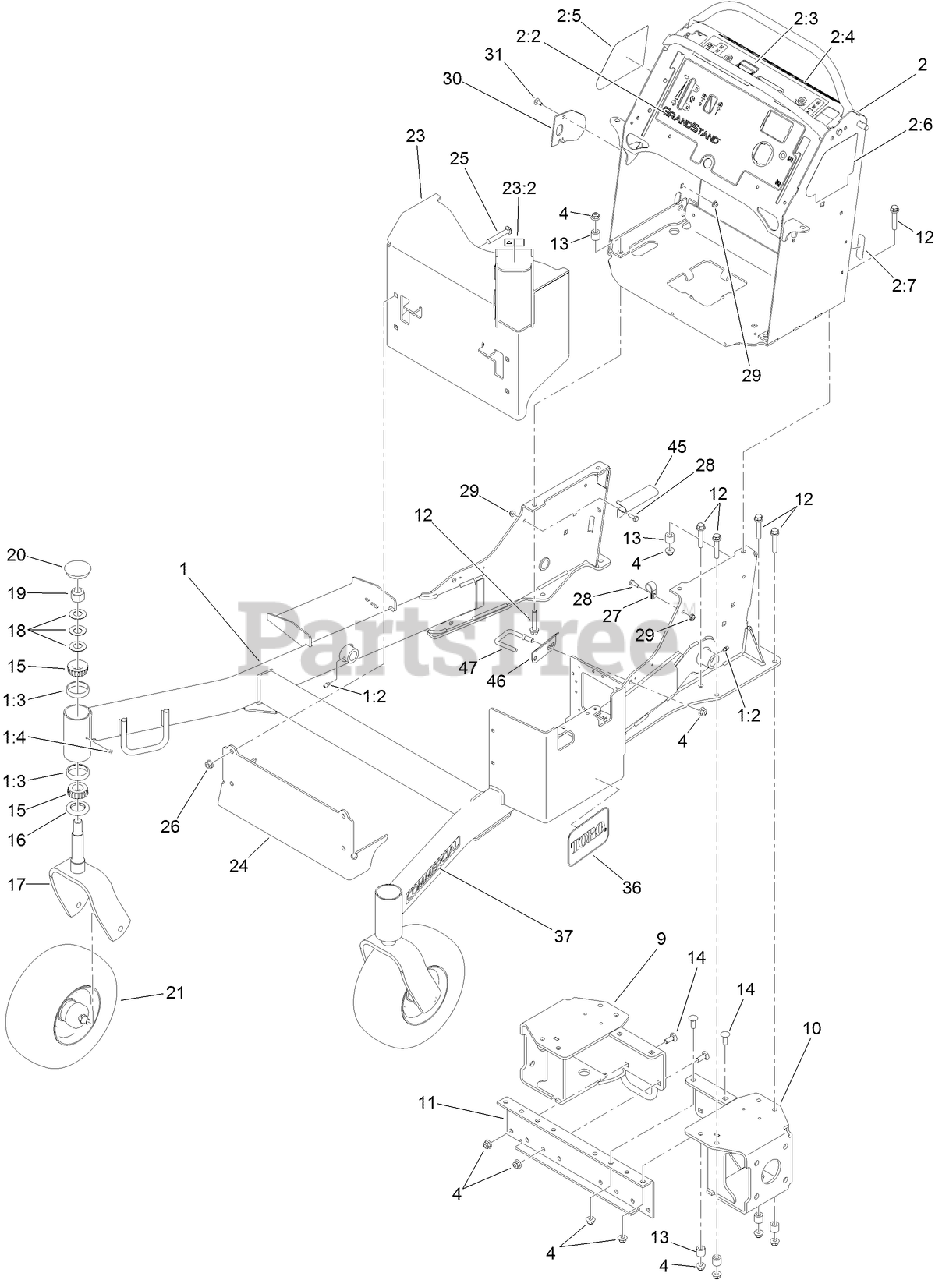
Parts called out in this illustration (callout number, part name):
1	FRONT FRAME ASM
1:2	FITTING-GREASE
1:3	CUP-BEARING
2	CONTROL TOWER ASM
2:2	DECAL-CONTROL PANEL, EFI
2:3	DECAL-OPC
2:4	DECAL-WARNING
2:5	DECAL-HOC
2:6	DECAL-SERVICE/SPARK ARREST
2:7	DECAL-FUSE
4	NUT-HF, NI
9	MOUNT-MOTOR, RH
10	MOUNT-MOTOR, LH
11	MOUNT-MOTOR, CENTER
12	SCREW-HHF
13	SPACER
14	SCREW-CARR
15	BEARING-ROLLER, TAPERED
16	SEAL-GREASE
17	FORK-CASTER
18	WASHER-BELLVILLE
19	NUT-LOCK, NI
20	CAP-GREASE
21	WHEEL/TIRE AND BEARING ASM
23	MUFFLER GUARD ASM
23:2	DECAL-WARNING
24	PANEL-GUARD
25	SCREW-CARR
26	NUT-HF
27	CLAMP-CABLE
28	SCREW-HH
29	NUT-HF
30	PLATE-STRIKER
31	SCREW-CARR
36	DECAL
37	DECAL-COMMERCIAL
45	BRACKET-HOSE, FUEL (DOUBLE)
46	GUARD-HOSE
47	GUIDE-HOSE
